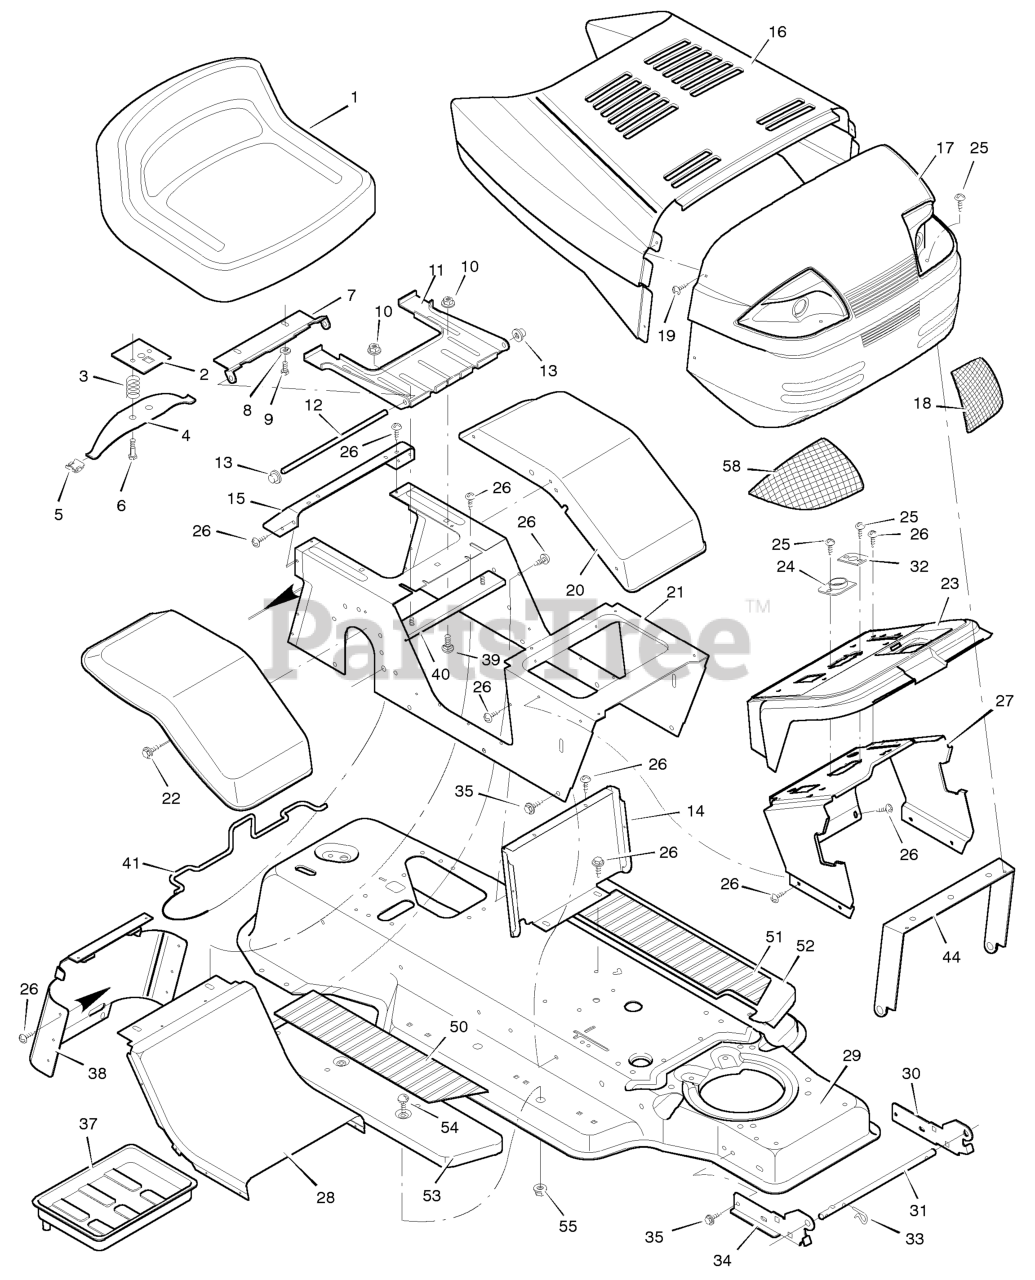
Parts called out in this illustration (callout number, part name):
2	Plate Assembly, Switch
3	Spring, Compression
4	Spring, Seat
5	Glide, Spring
6	Bolt, Shoulder
7	Support, Seat
8	Lockwasher
9	Bolt, Hex
10	Locknut, Flange
11	Bracket, Pivot
12	Rod, Pivot
13	Cap, Push On
14	Insert, Front
15	Fender, Apron
17	Grille Assembly
18	Lens, Left
21	Console Assembly
23	Dash Panel
24	Bearing, Steering
26	Screw
27	Support, Dash
28	Insert, Rear
29	Frame Assembly
30	Bracket, Left Grille
31	Rod, Pivot
32	Bearing
33	Pin, Hair
34	Bracket, Right Grille
37	Tray, Battery
38	Cap, Console
39	Bolt
40	Channel Assembly
41	Clamp, Battery
44	Brace, Grille
46	Bolt, Hex
50	Mat, Right
51	Mat, Left
52	Running Board, Left
53	Running Board, Right
54	Bolt, Carriage
55	Nut, Flange
58	Lens, Right
